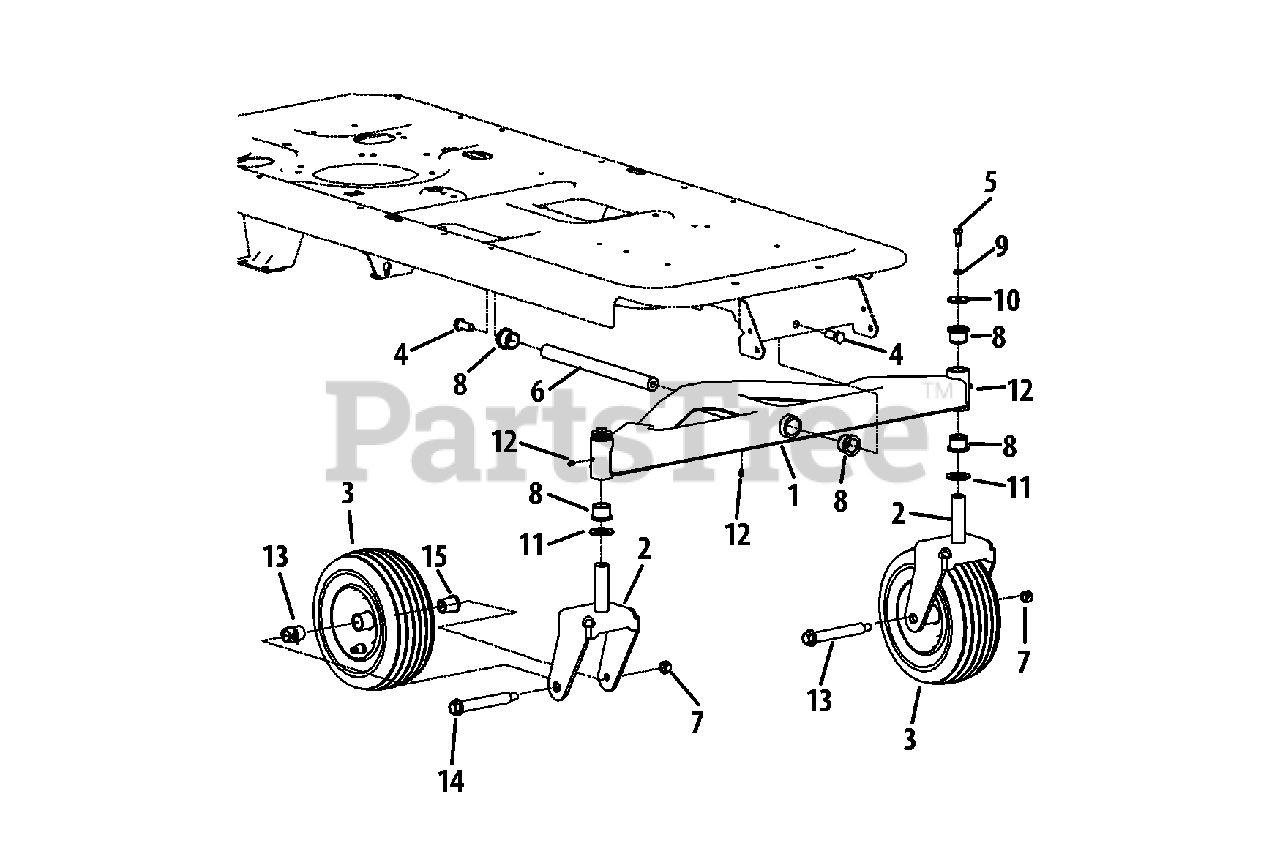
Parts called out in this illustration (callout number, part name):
1	Front Pivot Axle
2	Castor Wheel Bracket
3	Wheel Assembly, 11.0 x 4.0 x 5.0 Gray
4	Hex Lock Screw, 1/2-13 x 1.25
5	Hex Cap Screw, 3/8-16 x 1.0
6	Axle Shaft
7	Hex Lock Nut, 1/2-13
8	Flange Bearing, 1.0 x 1.246
9	Lock Washer, 3/8
10	Flat Washer, .39 x 1.5 x .134
11	Flat Washer, 1.0 x 1.75 x .107
12	Lube Fitting, 3/16 Drive
13	Shoulder Screw, .75 x 4.75 x 7/16-14
14	Flange Bearing, .76 x 1.0 x 1.2
15	Flange Bearing, .76 ID w/ Lube Ftg.
